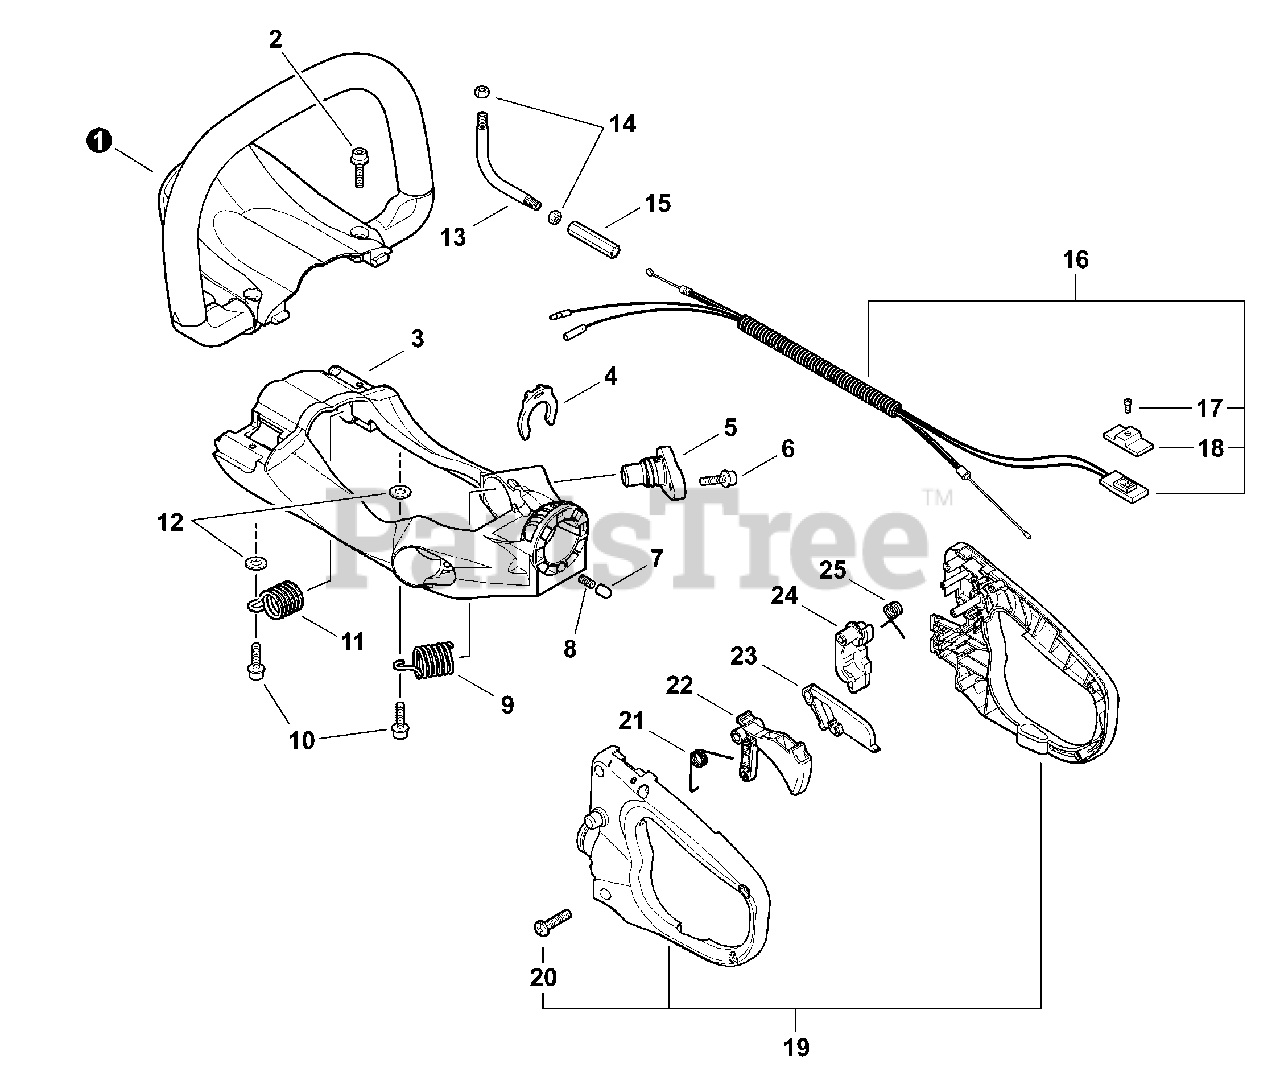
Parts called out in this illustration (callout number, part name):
1	HANDLE, FRONT
2	BOLT 5×20
5	HOLDER, SPRING
6	BOLT 5×20
7	PIN, CLEVIS
8	SPRING, COMPRESSION
9	SPRING, COMPRESSION
10	BOLT 5×16
11	SPRING, COMPRESSION
12	WASHER 5.5×12×0.8
13	TUBE, THROTTLE CABLE
14	NUT 3N-7
15	CONNECTOR
16	CONTROL CABLE ASSY
17	SCREW 3×10
18	KNOB, SWITCH - ORANGE
19	REAR HANDLE SET
20	SCREW 4×16
21	SPRING, TORSION
22	TRIGGER, THROTTLE
23	LOCKOUT, THROTTLE
24	LEVER, HANDLE RELEASE
25	SPRING, TORSION
